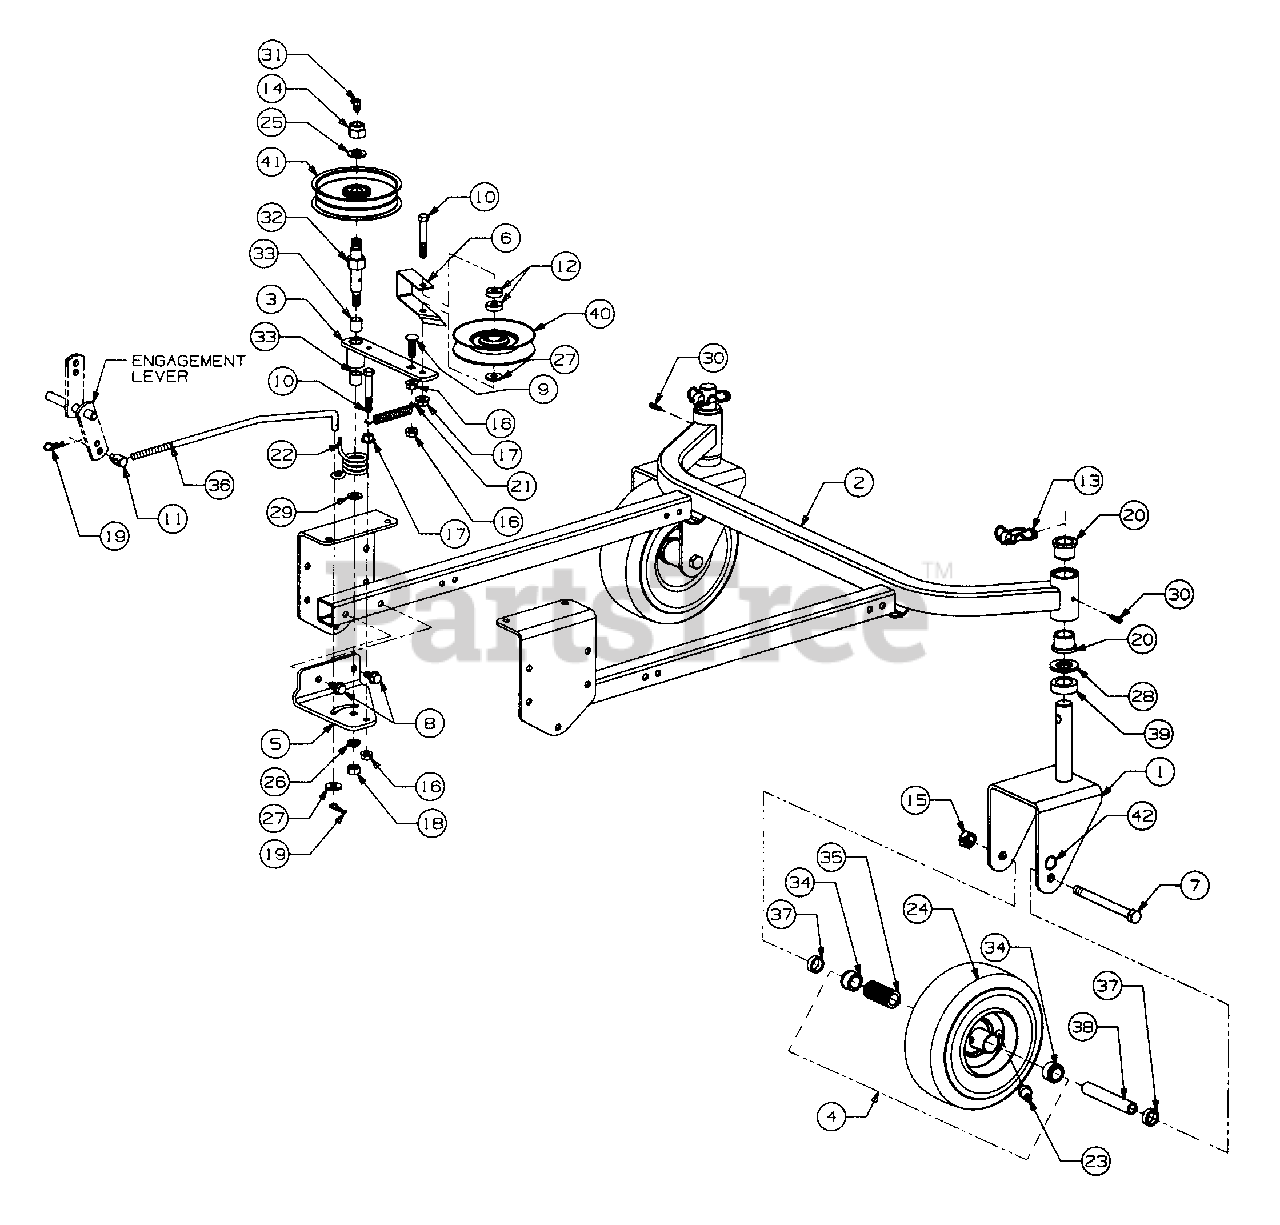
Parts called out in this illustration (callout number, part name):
2	Cradle Assy, Fixed
3	Arm Assy, Idler [lncludes Ref No. 33 (Qty 2)]
4	Wheel Assy, Caster
5	Bracket, Manual PTO Idler
6	Guide, Belt
7	Screw, Hex Cap, 1/2-20 X 5.50 Lg
8	Screw, Hex Wash Sf Tap, 3/8-16 X .75 Lg
9	Bolt, Carriage, 3/8-16 X 1.25 Lg GR5
10	Screw, Hex Cap, 3/8-16 X 2.50 Lg GR5
11	Ferrule, 3/8-24 X .37 Dia
12	Spacer, .380 X 1.00 X .32
13	Pin, Klik
14	Nut, Hex Nylon Insert Lock, 5/8-1 8
15	Nut, Hex Center Lock, 1/2-20
16	Nut, Hex Flanged Lock, 3/8-16
17	Nut, Hex Flange Lock, 3/8-1 6 GR5
18	Nut, Hex, 7/16-14 GR5
20	Bearing, Flange
21	Spring, Extension
22	Spring, Torsion
23	Valve, Tubeless Air
24	Tire, Smooth, 9.0 X 3.50 X 4
25	Washer, Flat, .635 X 1.120 X .093 Thk
26	Washer, Lock, 7/16
27	Washer, Special, .385 X .87 X .06 Thk
28	Washer, Special
29	Washer, Flat, .469 X .875 X .105 Thk
30	Fitting, Lube
31	Fitting, Lube, 90ø 1/4-28 Tapper Thd
32	Bolt, Idler Mtg Shoulder
33	Bearing, Sleeve
34	Bearing, Graf Oil Flange
35	Bearing, Roller
36	Rod, PTO Engagement
37	Spacer, .790 ID X .347 Lg
38	Spacer, Wheel
39	Spacer, 1.015 X 1.62 X .50 Lg
40	Pulley, V-Idler
41	Pulley, Flat Idler, 5"
42	Label, Inflation
